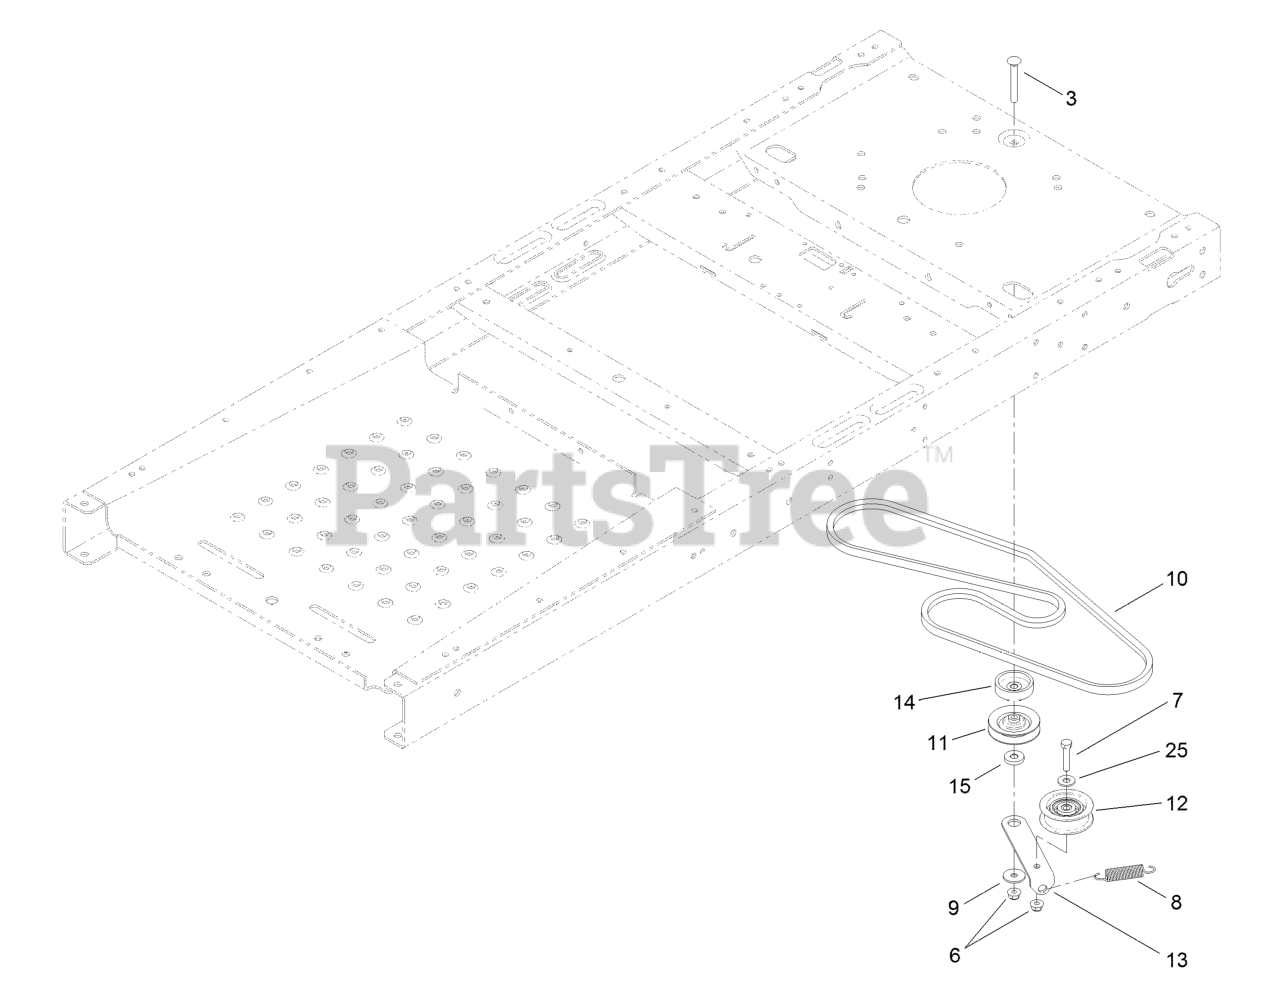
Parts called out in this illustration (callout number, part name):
3	SCREW-CARR
6	NUT-HF, NI
7	SCREW-HH
8	SPRING-RETURN, PEDAL
9	WASHER-PIVOT
10	V-BELT
11	PULLEY-IDLER
12	PULLEY-IDLER
13	ARM-IDLER
15	SPACER-ARM, IDLER
25	WASHER-FLAT
